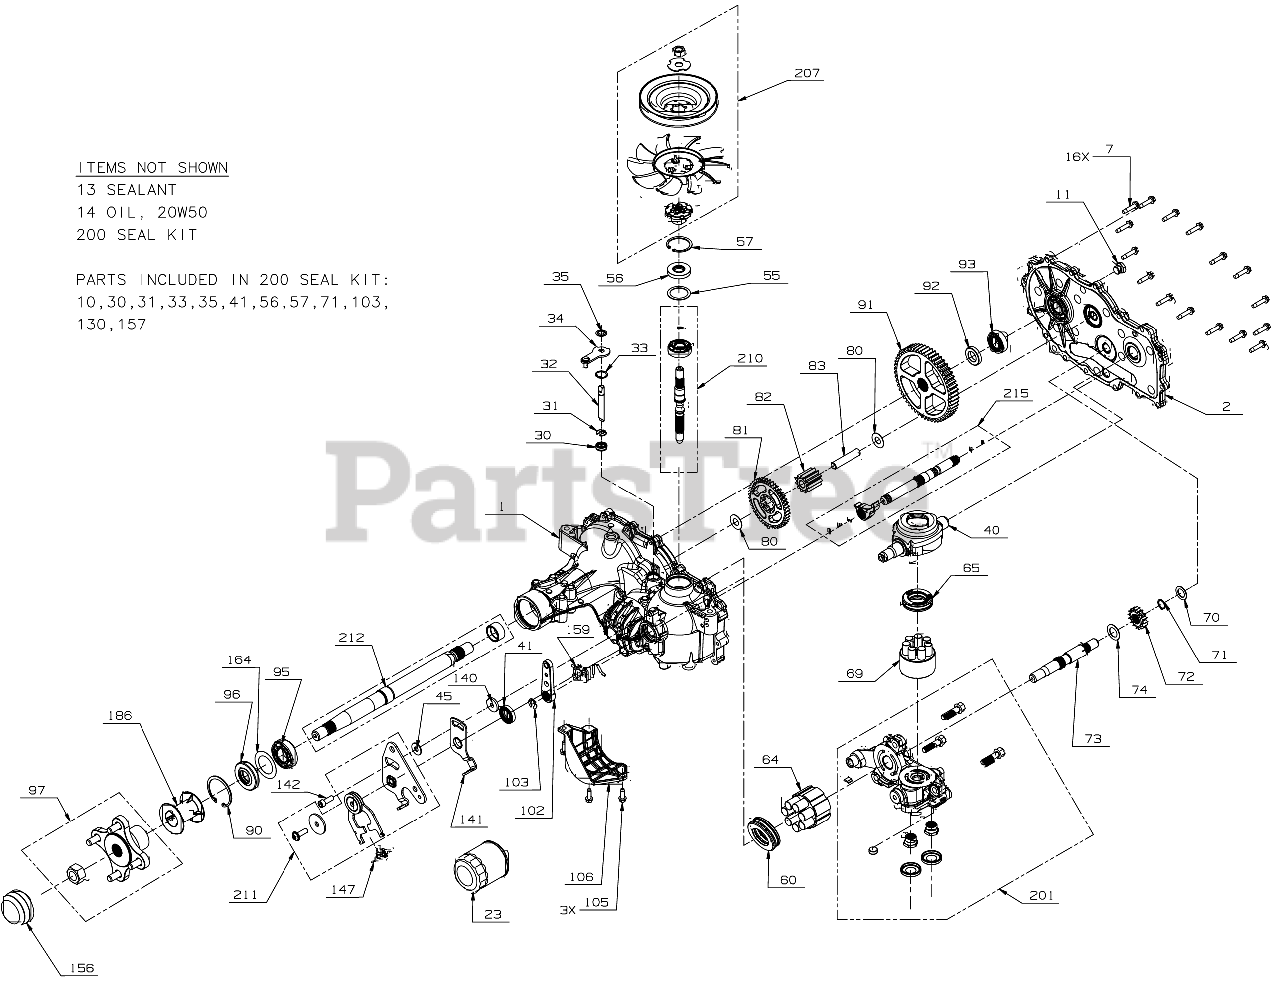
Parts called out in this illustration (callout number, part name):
1	HOUSING KIT-MAIN
2	COVER KIT-SIDE (RH)
7	SCREW-WASHER HEAD
11	VENT PLUG
13	SEALANT-HOUSING
23	OIL FILTER
30	SEAL-LIP .375
31	RETAINING RING
32	BYPASS RODS
33	RETAINING RING
34	ARM-BYPASS
35	RETAINING RING
40	SWASHPLATE-TRUNNION
45	FLAT WASHER
55	WASHER 1.23X1.56X
57	RETAINING RING
60	THRUST BEARING
64	CYLINDER BLOCK ASSEMBLY
65	THRUST BEARING
69	BLOCK KIT-7 PISTON
70	FLAT WASHER
71	RETAINING RING
72	GEAR-16 T
73	MOTOR SHAFT
74	MOTOR SHAFT WASHER
81	GEAR-43 T
82	GEAR-11 T
83	PIN-JACKSHAFT
90	RETAINING RING
91	GEAR-54 T
92	SPACER .75X1.32X.257
93	BALL BEARING
95	BALL BEARING
97	HUB-4 BOLT WHEEL
102	BRAKE LEVER
103	RETAINING RING
106	GUARD-FILTER (RH)
140	SPACER .32 x 1.005 x .179
141	ARM-NEUTRAL (RH)
142	SCREWS KIT-RTN
147	EXTENSION SPRING
156	COVER-NUT
159	TORSION SPRING CCW
186	TUBE-AXLE 2.03
200	SEAL KIT
201	SECTION KIT-CENTER
207	KIT-FAN & PULLEY
207	FAN-7.0 (10 BLADE)
207	HUB-PULLEY
207	WASHER-SLOTTED
209	PULLER KIT-HUB
210	SHAFT KIT-INPUT
211	RETURN KIT-NEUTRAL (RH) ZT2800 RZT
212	SHAFT KIT-AXLE
215	OUTPUT SHAFT KIT (RH)
